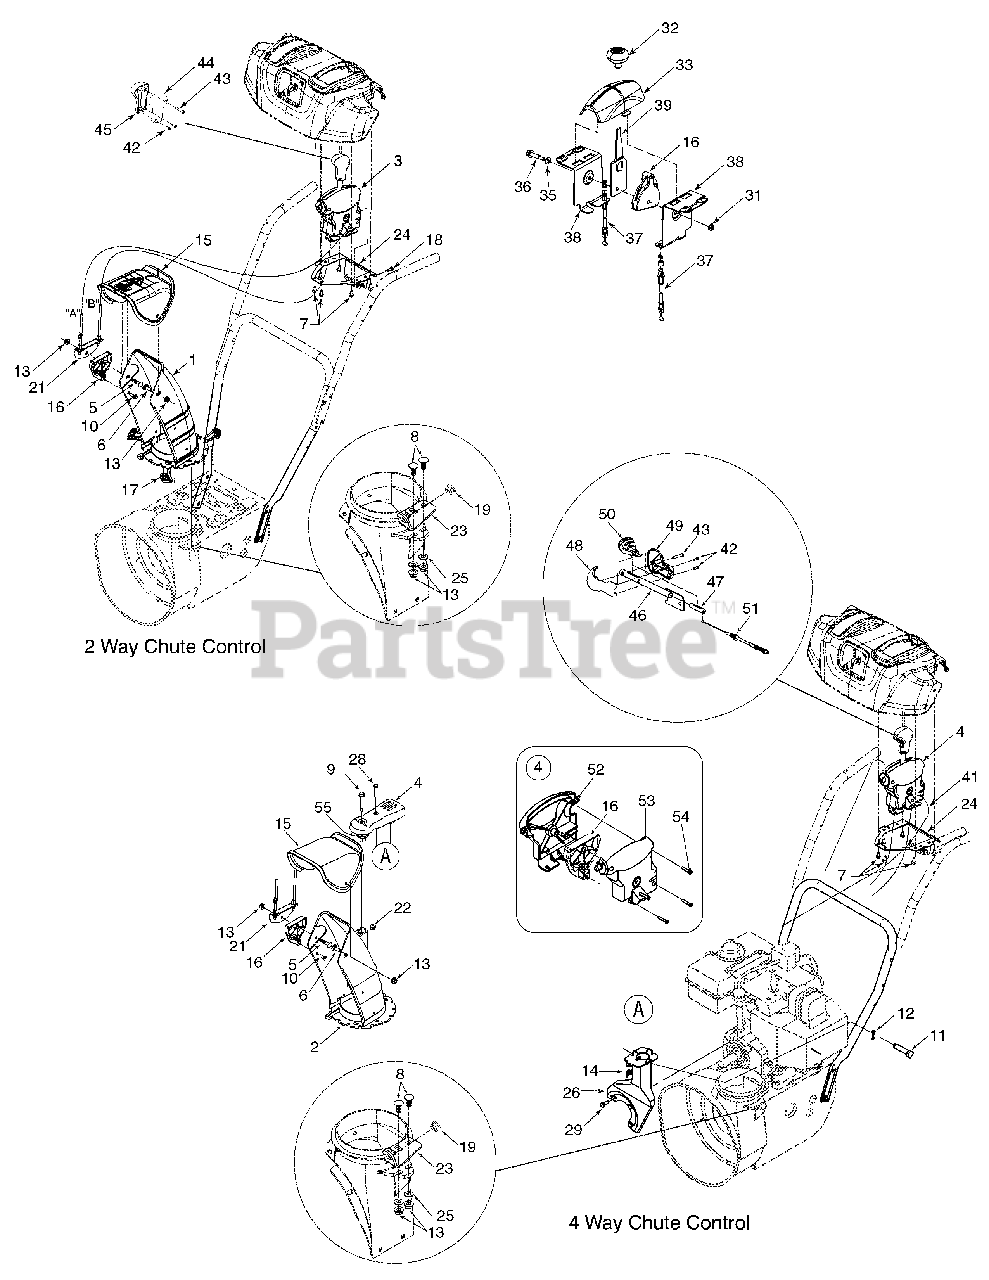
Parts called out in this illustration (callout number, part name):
1	Lower Chute (2 Way)
2	Lower Chute (4 Way)
3	2 Way Chute Control Assembly
4	4 Way Chute Control Assembly
5	Carriage Bolt 5/16-18 x 1.50 Gr. 2
6	Carriage Screw 5/16-18 x 1.0
7	Hi-Lo Screw 1/4-15 x .5
8	Carriage Bolt 5/16-18 x 1.00" Lg
9	Shoulder Screw .312 x 1.7:1/4-20
10	Hex Tapp Scr 1/4 x .75" Lg.
11	Clevis Pin 3/8 x 1.87
12	Bow Tie Cotter Pin
13	Flange Locknut 5/16-18 Gr. F Nylon
14	Wing Nut 1/4-20
15	Upper Chute w/Export Label, Remote
17	Chute Flange Keeper
18	Shoulder Screw .25 x .50:10-24
19	Plastic Bushing .380 ID
22	Hex L-Flanged Nut 1/4-20 Gr. F Nylon
25	Flat Washer .349 ID x .879 OD x .063
28	Hex Hd. Cap Screw 1/4-20 x 1.5 Gr. 5
29	Hex Hd. Cap Screw 5/16-24 x .75
30	Flat Washer .25 ID x .63 OD x .0515
31	Flange Locknut 1/4-20 Gr. F, Nylon
33	Control Cover - 2 Way
35	Spring Washer .390 x .625 x .012
36	Flg Shlder Spacer .310 x .995 x 1/4-20
37	Cable - 2 Way
40	Joystick Pulley
41	Chute Rotation Cable
42	Plastite Screw #6 x .375
43	Plastite Screw #8 x 1.00
44	RH Control Knob
45	LH Control Knob
46	Tube & Brkt. Lever Ass'y
47	Plunger
48	RH Trigger Control Knob
49	LH Trigger Control Knob
50	Trigger Levier
51	Detent Cable
52	Control Head Housing LH
53	Control Head Housing RH
54	Screw #8 x 1.0 Plastite
55	Joystick Pulley
